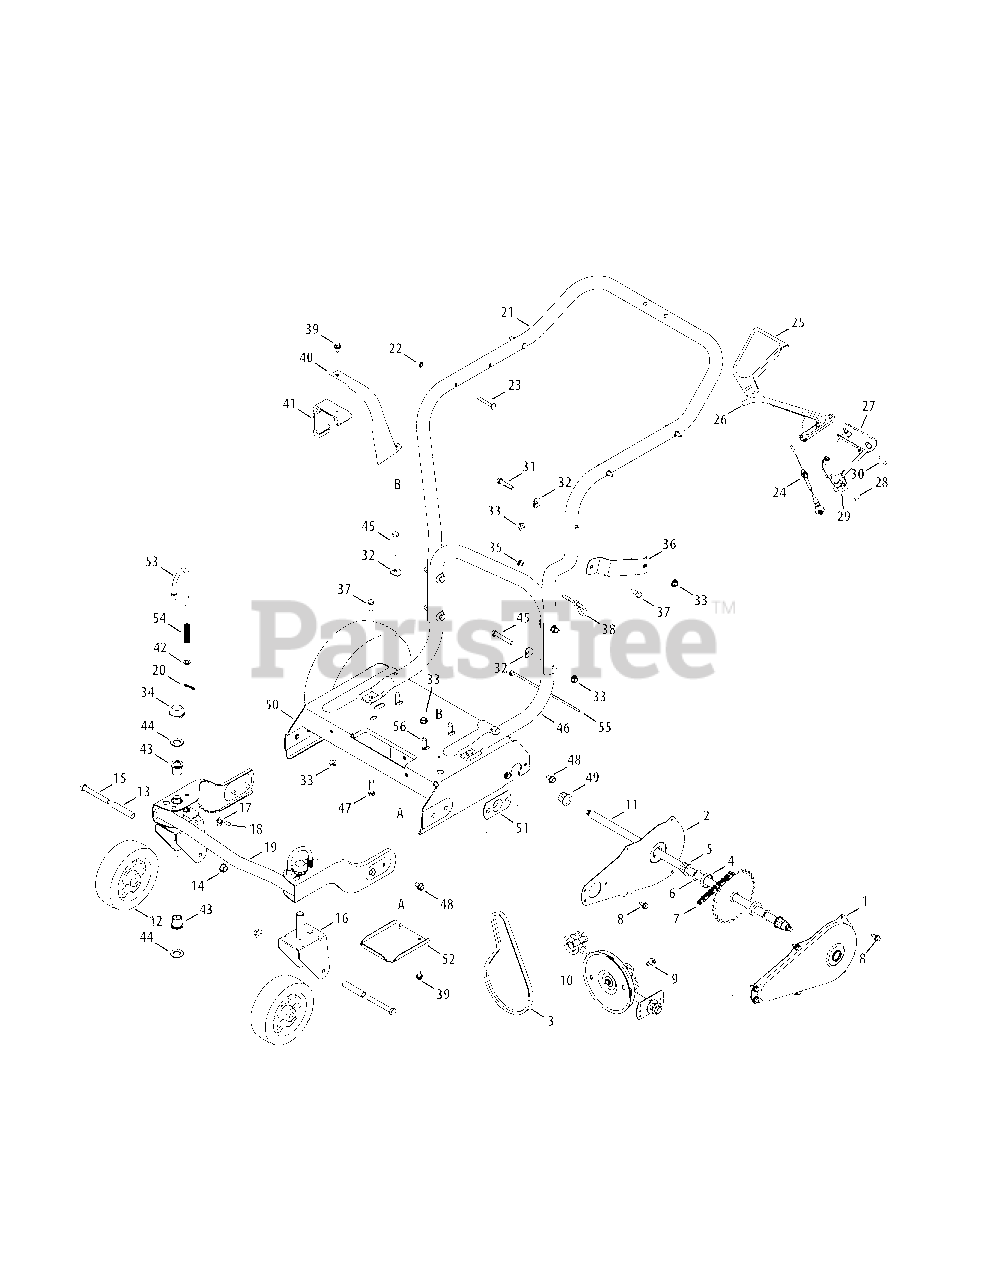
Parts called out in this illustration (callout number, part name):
1	Chain Case - LH
2	Chain Case - RH
5	Hex Flange Bearing
6	Flat Washer
8	TT Screw, 1/4-14 x 0.625"
9	Hex Washer Screw, 5/16
10	Chipper Shredder Trans. Ass’y.
11	Axle Assembly
12	Wheel, 6.0 x 2.0
14	Flange Lock Nut, 3/8-16
15	Hex Cap Screw, 3/8-16 x 3.0
16	Bracket Assembly
17	Flat Washer, .203 ID x.403 OD
18	Grease Fitting, 3/16
19	Bracket Assembly
20	Cotter Pin
23	Stud Pin, .250 x 1.75
24	Clutch Cable - 56"
25	Upper Clutch Cover
26	Drive Lever
27	Lower Clutch Cover
28	Screw, #10-12 x.750
29	Mounting Cable Cap
30	Screw, #10-16 x 1.25
31	Hex Cap Screw, 5/16-18 x 1.50
32	Shldr. Washer, .320 ID x.93 OD
33	Hex Flange Lock Nut, 5/16-18
35	Hex Nut, 1/4-28
36	Discharge Chute Bracket
37	Hex Cap Screw, 5/16-18 x.75
39	Hex Washer Screw, 1/4-14 x.625
40	Belt Cover
41	Engine Mounting Adapter
42	Flat Washer, .330 ID x.630 OD
43	Flange Bearing, .632 ID
44	Flat Washer, 5/8 ID x 1.0 OD
45	Hex Cap Screw, 5/16-18 x 1.75
46	Lower Push Handle
47	Screw, 3/8-16 x 1.25
48	Hex Wash. Screw, 5/16-18 x.625
49	Hex Flange Bearing, .631 x.720
50	Frame Assembly
52	Transmission Cover
54	Compression Spring
55	Cable Tie
56	Hex Cap Screw, 5/16-18 x 1.25
